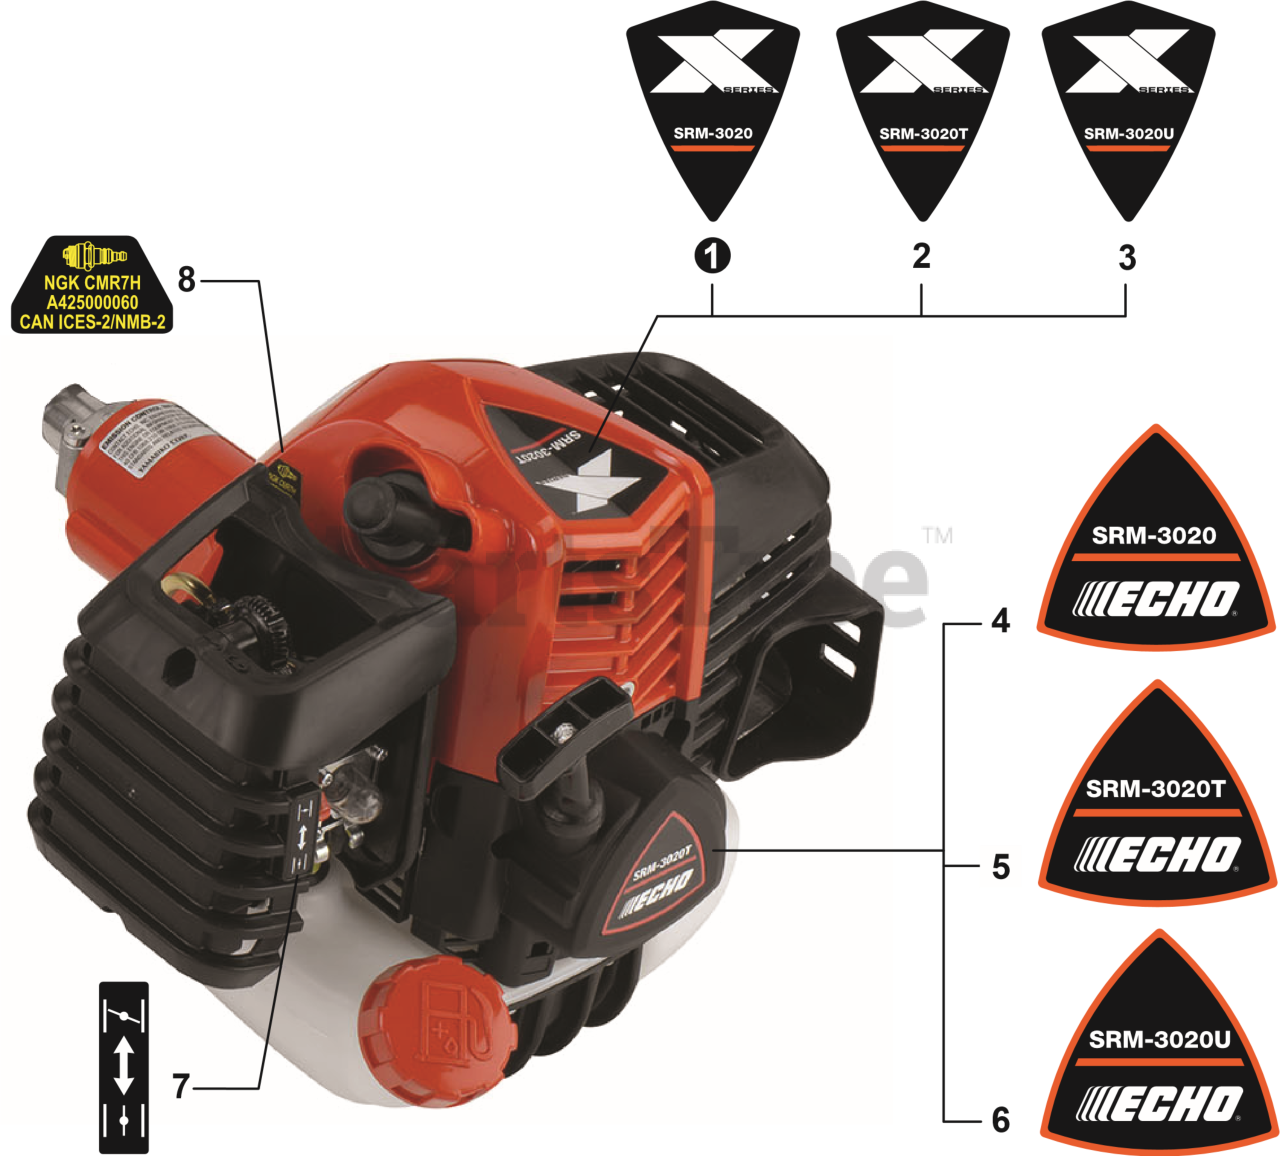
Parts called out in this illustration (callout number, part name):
1	LABEL - MODEL SRM-3020
2	LABEL - MODEL SRM-3020T
3	LABEL - MODEL SRM-3020U
4	LABEL - STARTER - SRM-3020
5	LABEL - STARTER - SRM-3020T
6	LABEL - STARTER - SRM-3020U
7	LABEL - CHOKE
8	LABEL - SPARK PLUG - CMR7H
